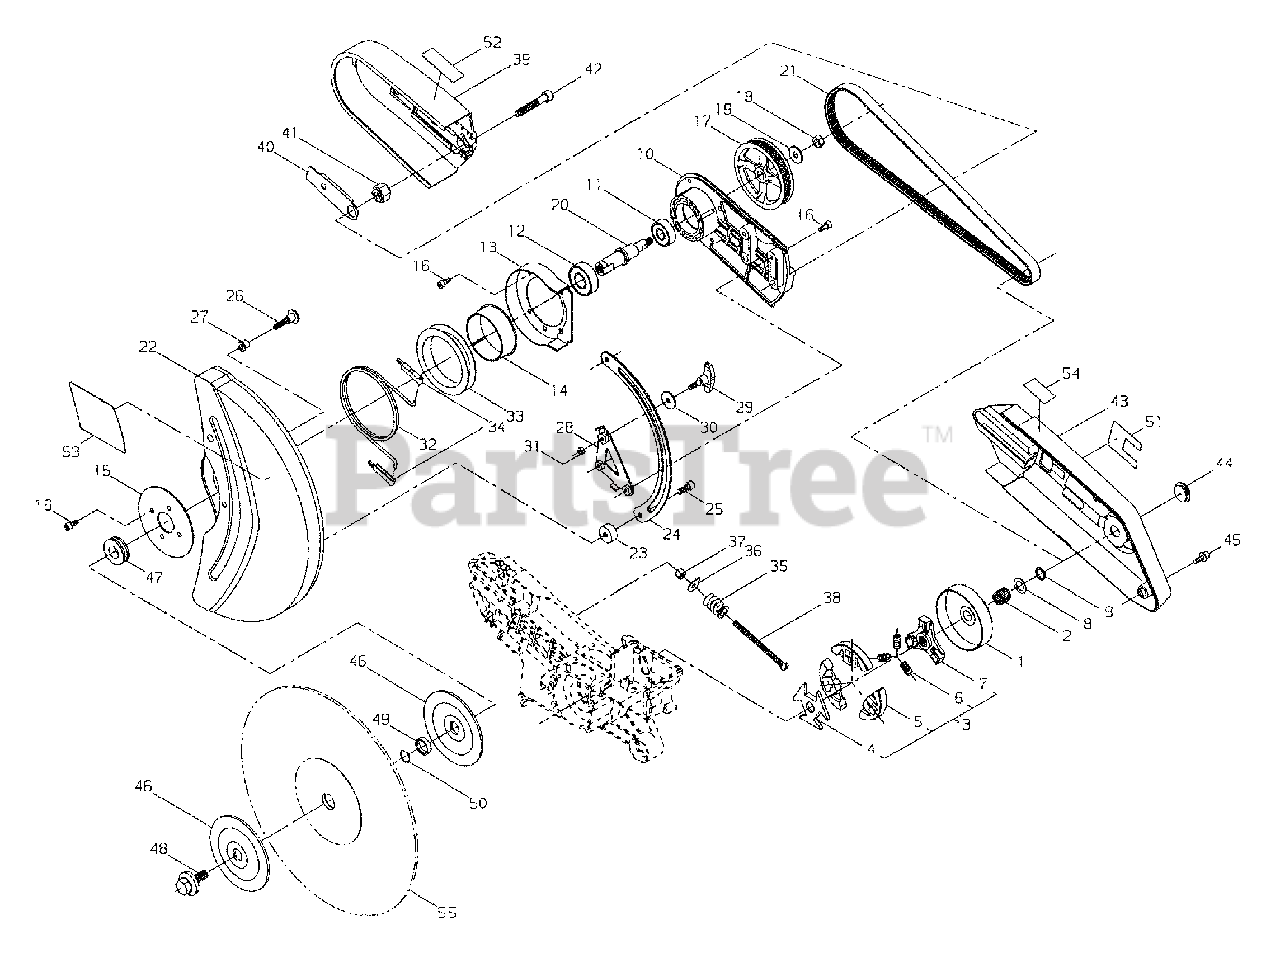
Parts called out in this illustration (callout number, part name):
1	DRUM, CLUTCH
2	BEARING, NEEDLE
3	CLUTCH ASSY
4	HUB, CLUTCH - OUTER
5	SHOE, CLUTCH
6	SPRING, CLUTCH
7	HUB, CLUTCH - INNER
8	PLATE, THRUST
9	RING, RETAINING - 13
10	CASE, BEARING
11	BEARING, BALL - 6201
12	BEARING, BALL - 6203
13	PLATE, SPRING
14	RING
15	PLATE, BEARING
16	SCREW - 5X16
17	PULLEY, DRIVE
18	NUT - 8
19	COLLAR
20	DRIVESHAFT
21	BELT, DRIVE
22	GUARD, WHEEL
23	COLLAR
24	SLIDE PLATE
25	SCREW - 6X20
26	BOLT, CLUTCH
28	PLATE, LOCK
29	KNOB
30	WASHER
31	NUT
32	SPRING
33	GUIDE, SPRING
34	SPRING HOLDER
35	SPRING
36	WASHER
37	NUT
38	SCREW
39	PULLY COVER
40	PLATE, TENSION
41	BLOCK, TENSION
42	SCREW - 8X50
43	COVER, CLUTCH
44	PLUG
45	SCREW - 5X14
46	FLANGE
47	COLLAR
48	BOLT - FLANGE
49	COLLAR
50	RING, RETAINING
51	LABEL - TRADE
52	LABEL - INSTRUCTION
53	LABEL - CAUTION
54	LABEL - ARROW
55	CUT OFF WHEEL
